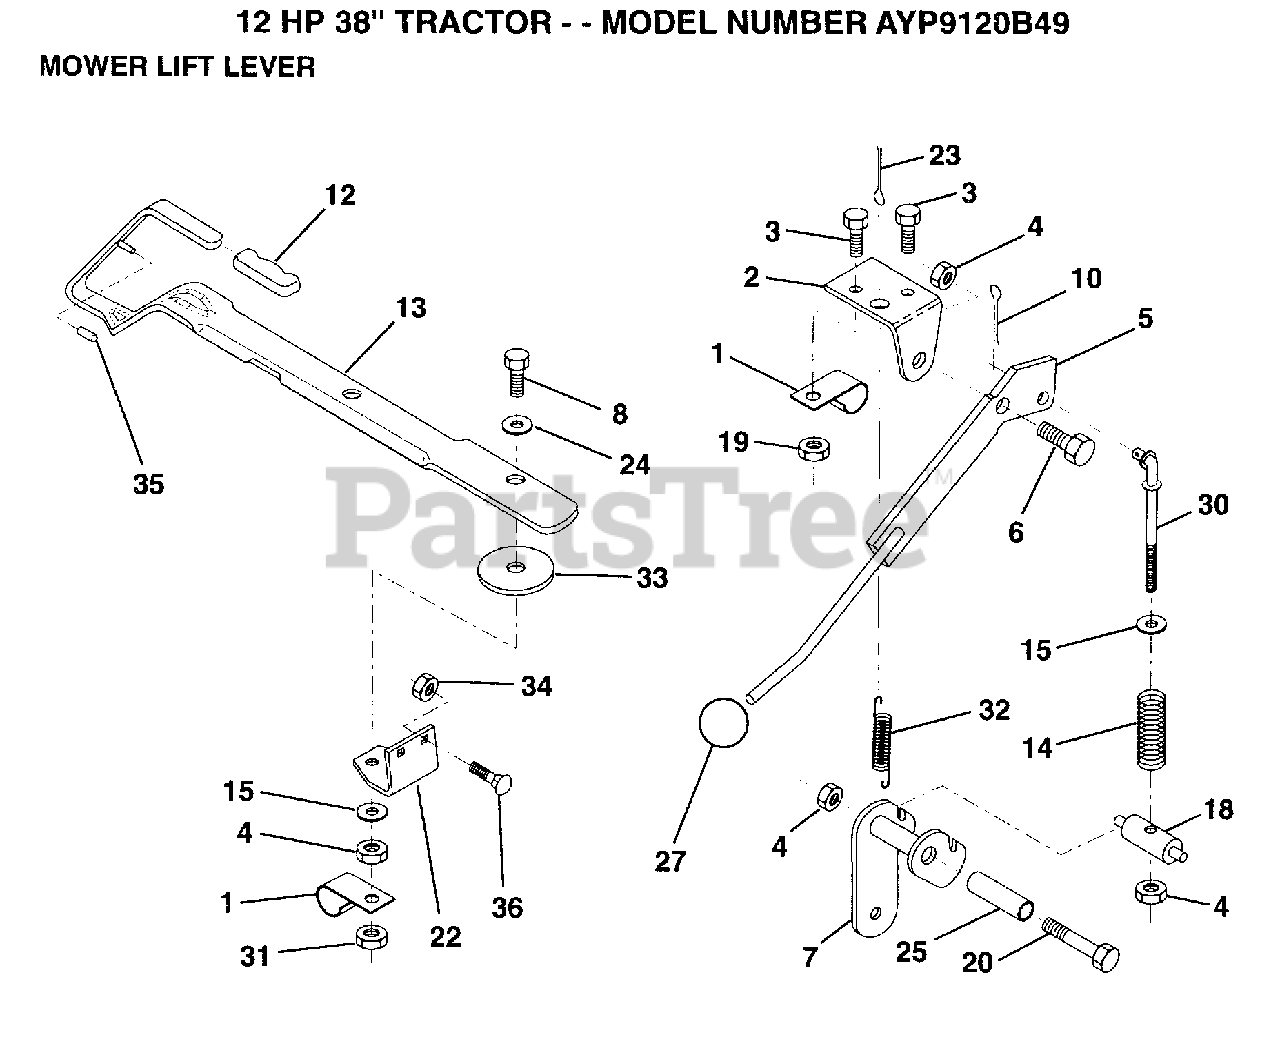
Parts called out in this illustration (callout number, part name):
1	"CLIP,INSULATOR"
2	BRKT CLUTCH
3	BOLT
4	NUT
5	CLUTCH LEVER AS
6	"BOLT, SHOULDER LT"
7	ARM.CLUTCH.ASM
8	BOLT
10	COTTER PIN
12	GRIP HANDLE
13	LEVER LIFT LR
14	COMP CLUTCH SPRNG
15	WASHER HYT
18	TRUNNION
20	BOLT
22	LIFT LEVER BRKT
24	WASHER
25	TUBE SPACER
27	KNOB T(3/8 HOLE)
30	ROD TENSION CLUTC
31	LOCKNUT
32	SPRING EXT
33	WASHER
34	NUT
35	VINYL CAP RED
36	BOLT
